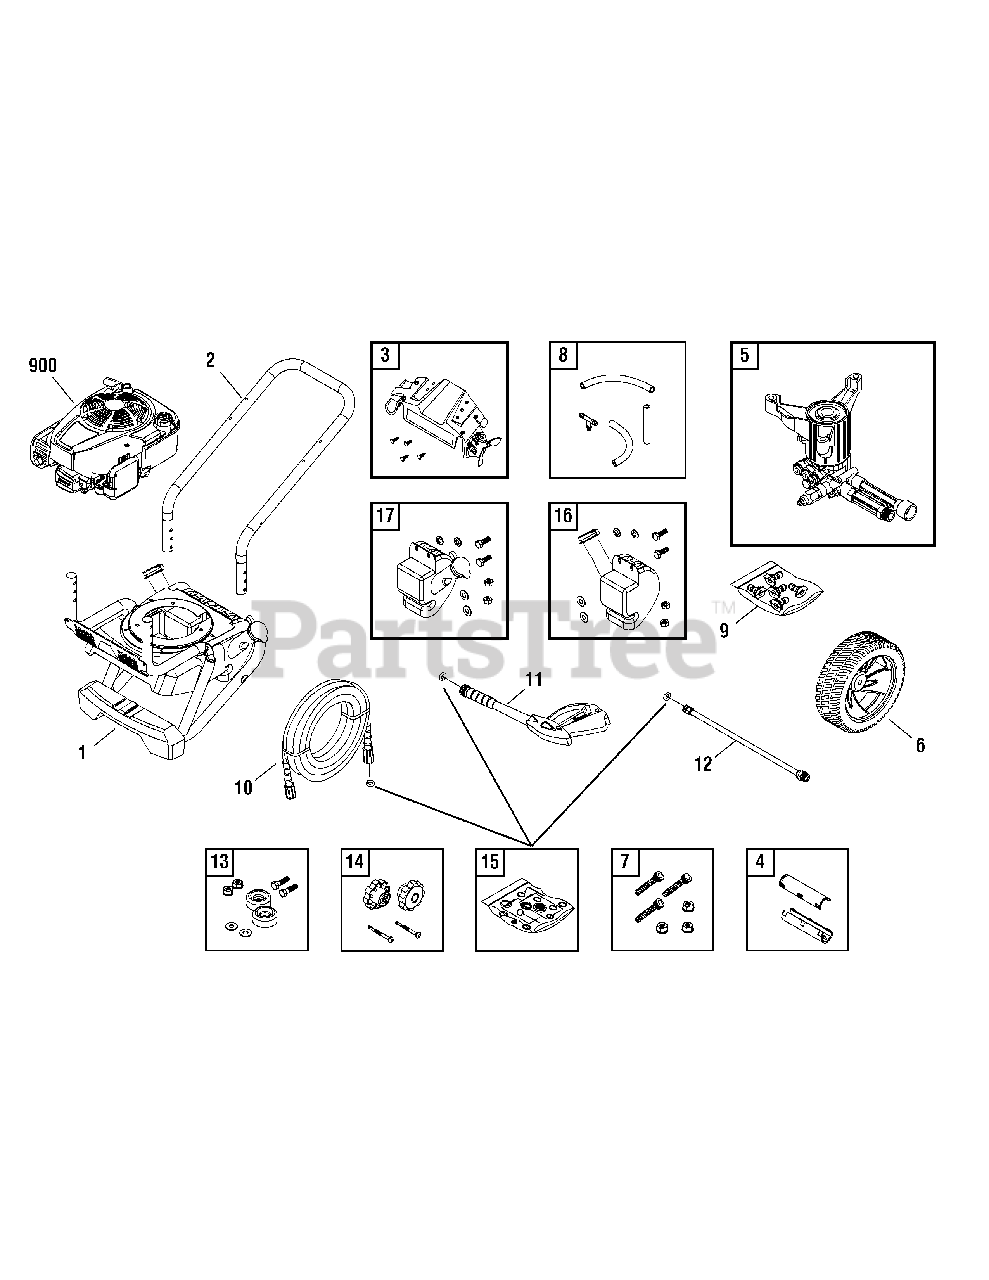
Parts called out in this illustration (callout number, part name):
7	KIT, Hardware, Pump Mounting
9	KIT, QC Nozzles
11	GUN
12	EXTENSION, QC
13	MOUNT, Vibration
14	KIT, Hardware, Handle
15	KIT, O-Ring
900	* ENGINE
